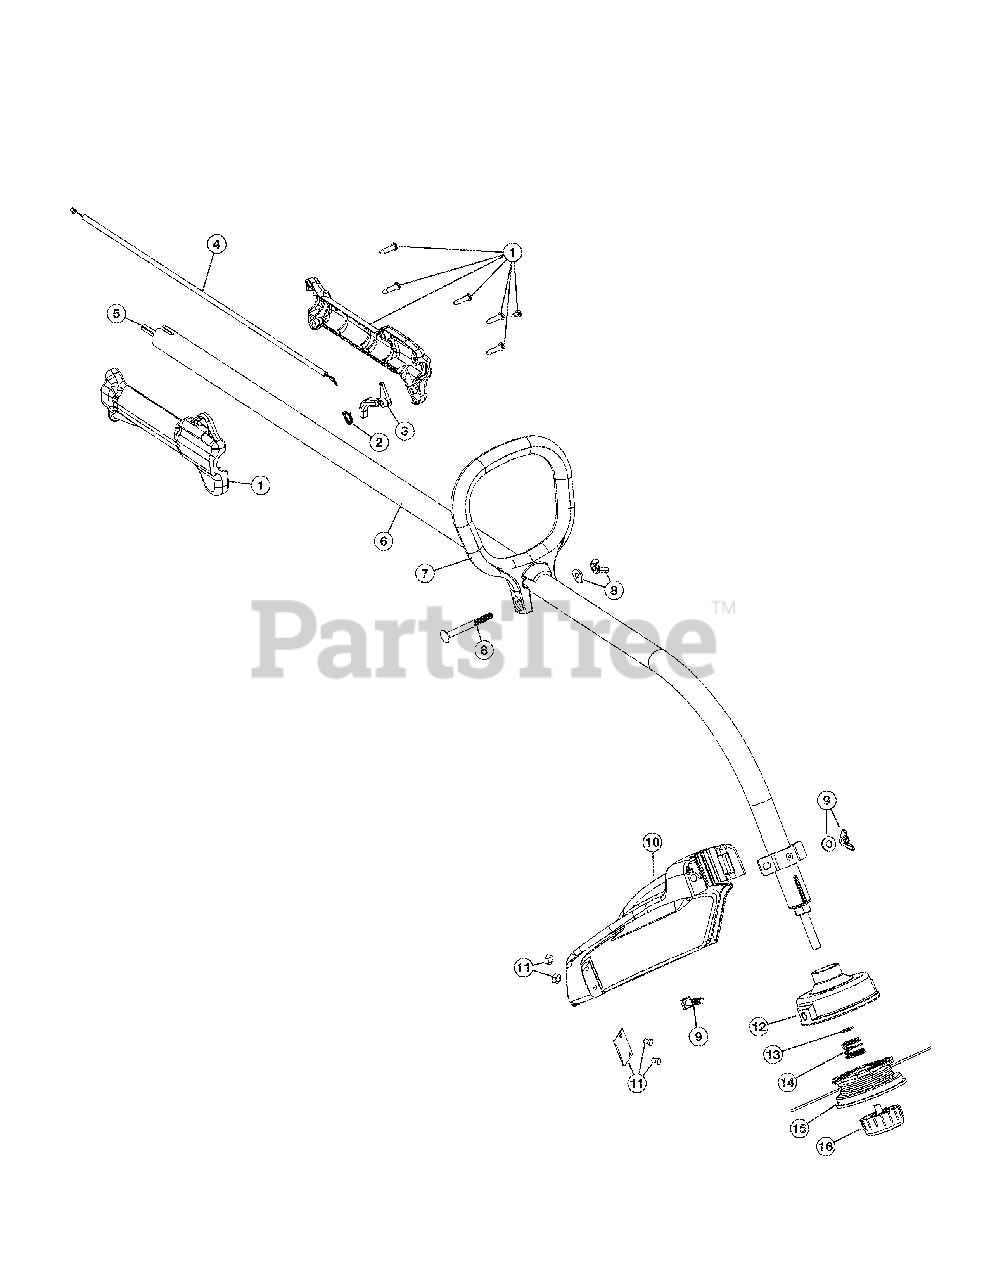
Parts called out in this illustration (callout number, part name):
1	Throttle Housing Assembly (includes 2 & 3)
2	Throttle Trigger Spring
3	Throttle Trigger
4	Throttle Cable
5	Flexible Drive Shaft
6	Drive Shaft Housing
7	D-Handle Assembly (includes 8)
8	D-Handle Hardware
9	Guard Mounting Hardware
10	Guard (includes 11)
11	Blade Assembly
12	Outer Reel (includes 13)
13	Retainer
15	Inner Reel
16	Bump Knob
